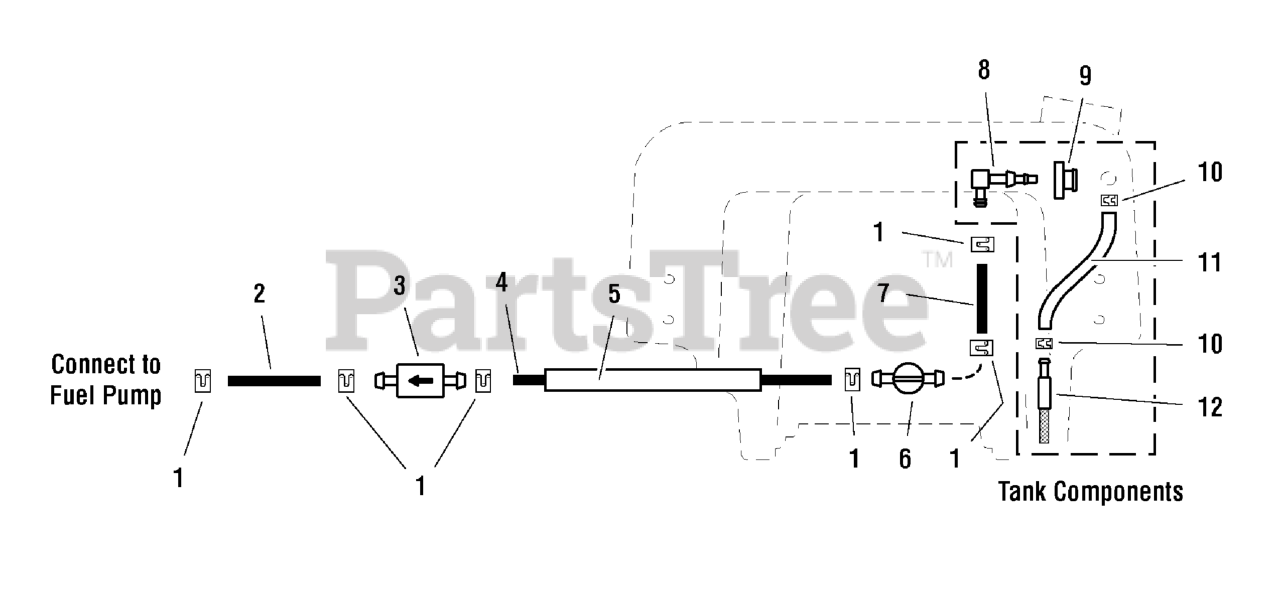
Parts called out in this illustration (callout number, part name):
1	CLAMP, HOSE, EXTERNAL, 1/2 - RED
2	HOSE, 1/4" FUEL, 7.00"
3	FUEL FILTER
4	HOSE, 1/4" FUEL, 35.00"
5	WIRE LOOM, 1/2" ID, 23" LONG
6	VALVE, FUEL SHUT OFF
7	HOSE, 1/4" FUEL, 5.00"
8	ELBOW FITTING
9	BUSHING-FUEL TANK RED RUBBER
10	SEE HOSE ASSEMBLY
11	ASSM, FUEL HOSE, 20"
12	SEE HOSE ASSEMBLY
